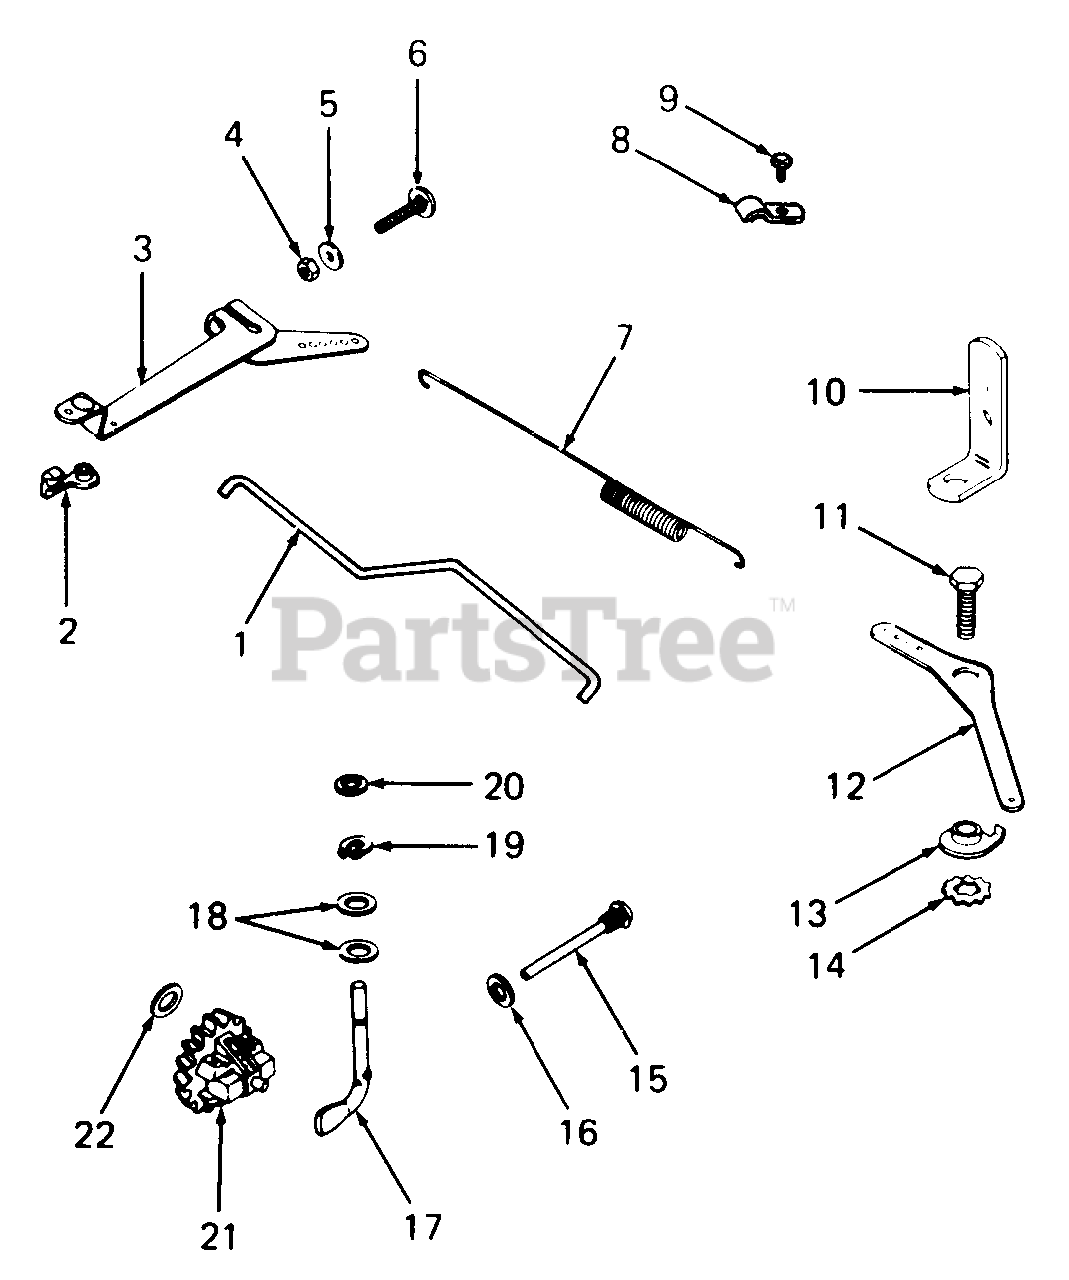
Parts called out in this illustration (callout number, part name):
1	Kit, Governor Linkage
2	Bushing, Linkage Retaining
3	Arm, Governor
4	Nut, Hex, 1/4-20
5	Washer, Plain, 1/4
6	Screw, Sq Neck, RH, 1/4-20 X 1.0 Lg
7	Spring, Governor
8	Clamp, Cable
9	Screw, Hex Wash Hd, #10-24 X .37 Lg
10	Bracket, Throttle Cable
11	Screw, Hex Cap, 1/4-20 X .62 Lg
12	Lever, Speed Control
13	Stop, Governor
14	Washer, Lock
15	Pin, Governor Stop
16	Washer, Plain, 1/4
17	Shaft, Governor Cross
18	Washer, Plain, 1/4
19	Retainer, Governor
20	Washer, Plain, 1/4
21	Kit, Governor Gear
